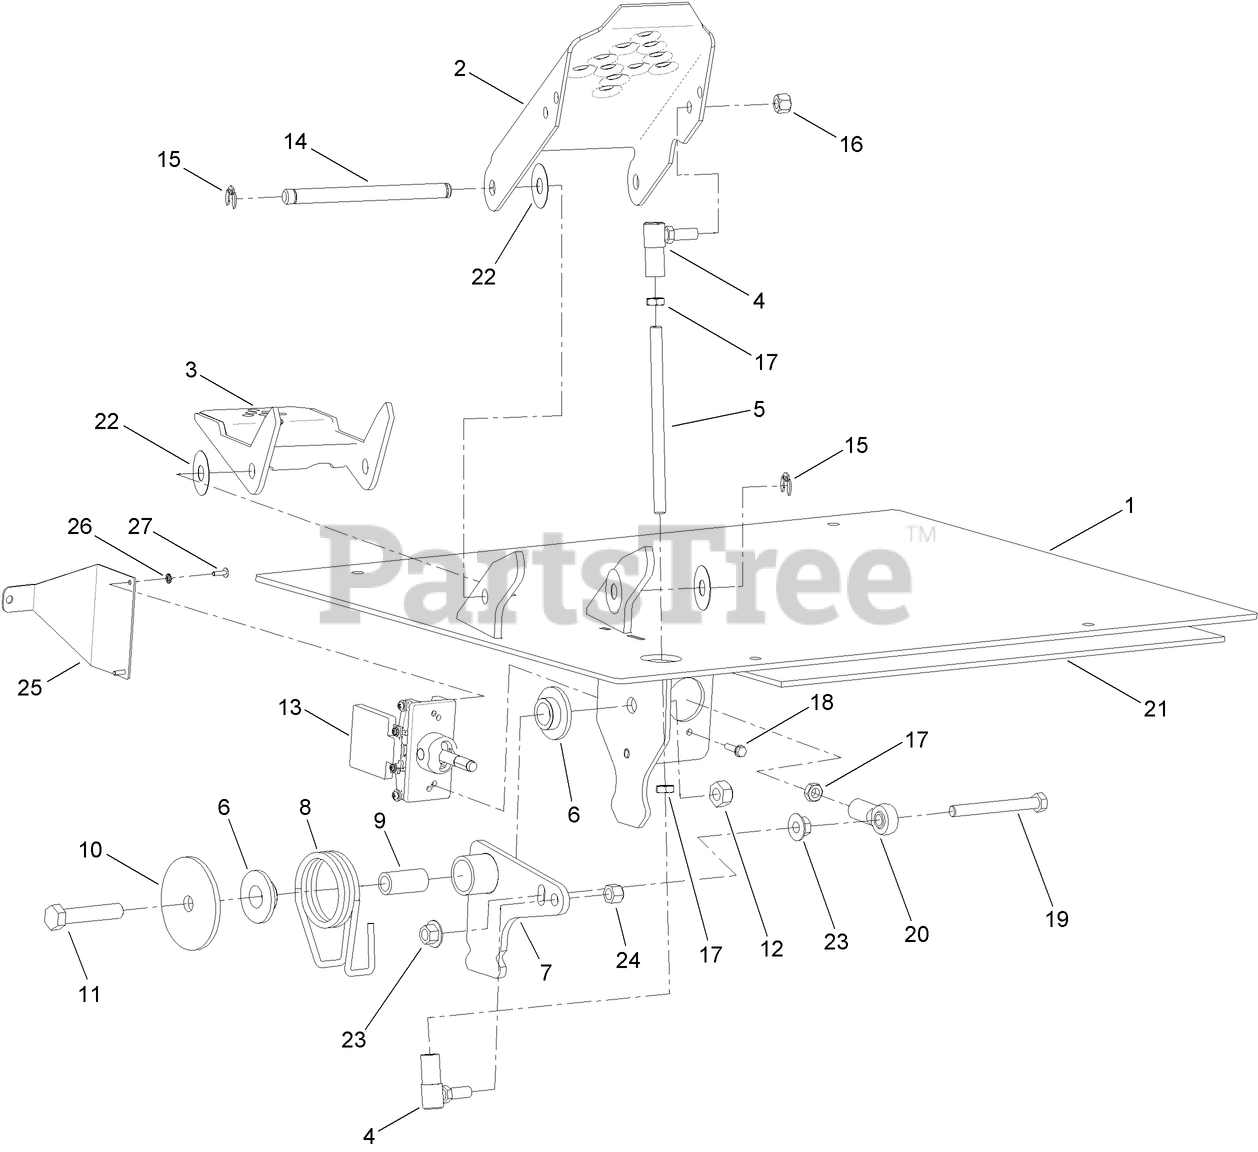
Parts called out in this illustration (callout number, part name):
1	PLATE-FLOOR
2	PEDAL-FOOT, GROUND DRIVE
3	PEDAL-HEEL
4	JOINT-BALL
5	ROD-CONTROL
6	BUSHING-INSERT, PLASTIC
7	PIVOT-W/BELLCRANK
10	WASHER-Special
11	SCREW-HH
12	LOCKNUT
13	SENSOR-TRACTION
15	RING-CLIP, LOCKING
16	NUT-HEX
17	NUT-HJ
18	TSCREW-HWH
19	SCREW-HH
20	ROD-END
21	INSULATION-FLOOR
22	WASHER
23	NUT-FLANGE
24	NUT-LOCK
25	PLATE-SENSOR, PEDAL
26	WASHER-LOCK / EXT
27	SCREW-PRH
